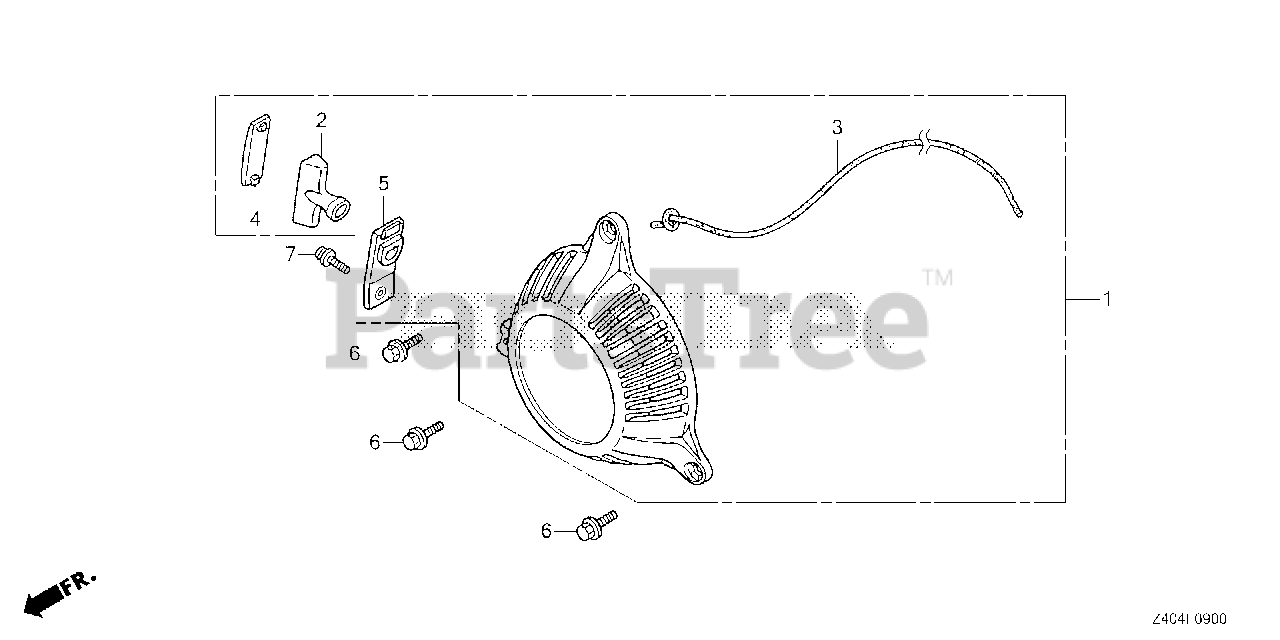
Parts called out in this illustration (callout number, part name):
1	STARTER ASSY., RECOIL
1	STARTER ASSY., RECOIL (COO)
1	KNOB, RECOIL STARTER
2	GRIP, STARTER
2	GRIP, STARTER (COO)
3	ROPE, RECOIL STARTER
4	COVER, GRIP
5	GUIDE, STARTER ROPE
6	BOLT, FLANGE (5X10)
7	SCREW-WASHER (5X10)
